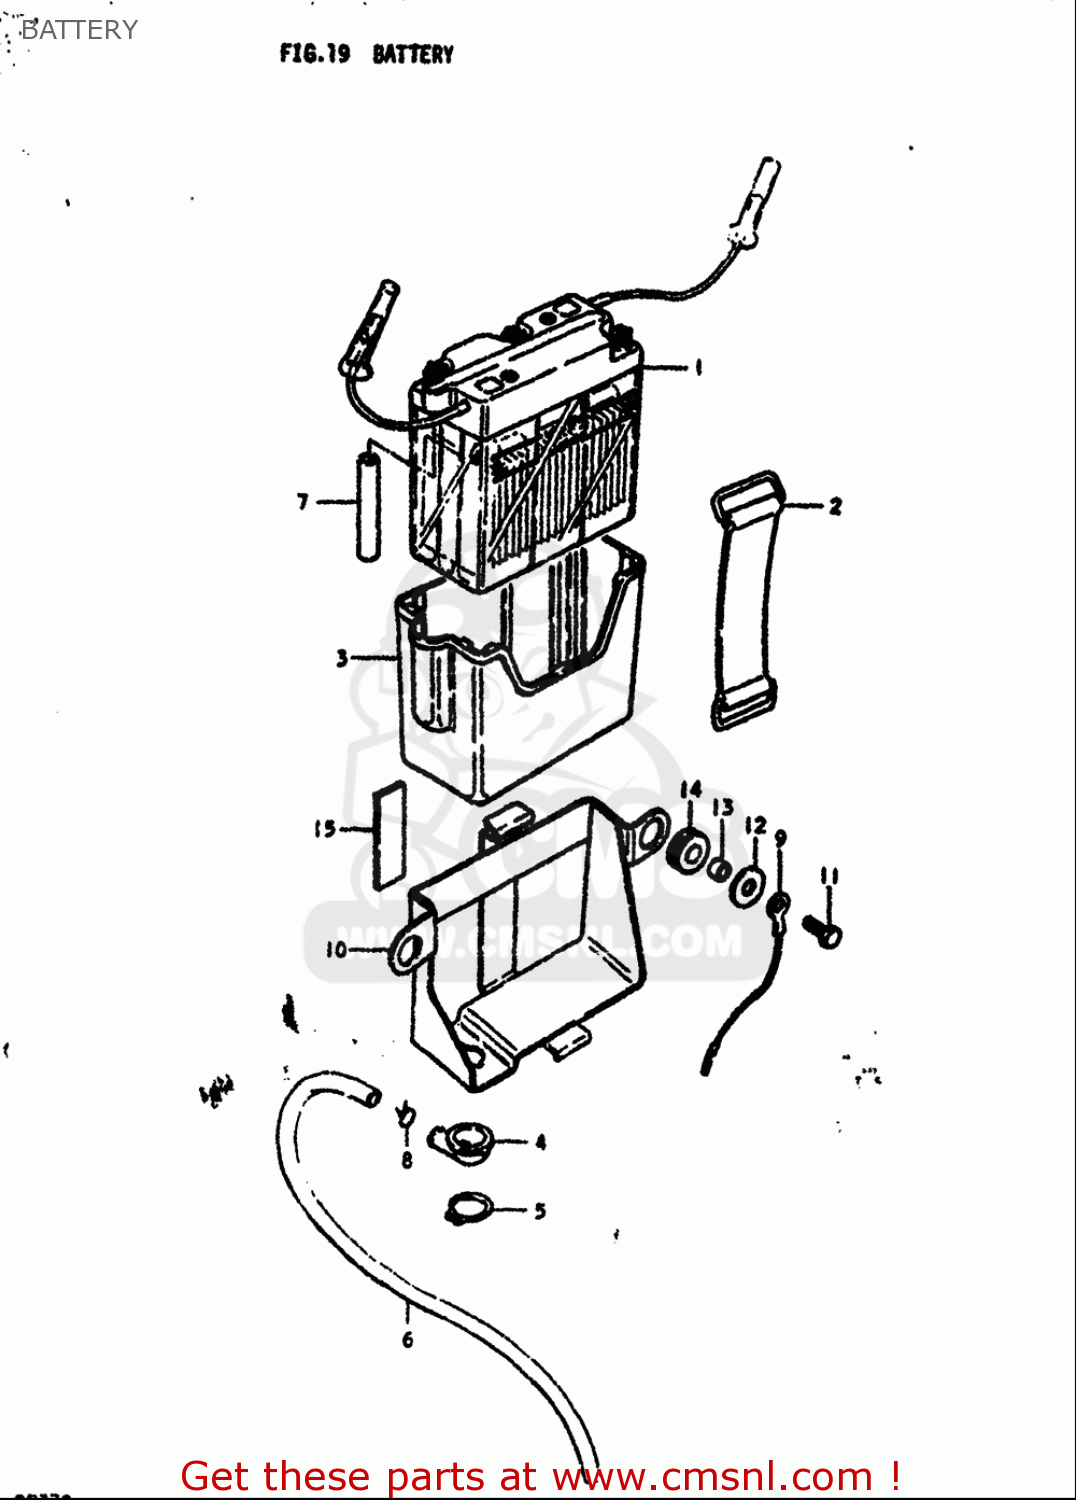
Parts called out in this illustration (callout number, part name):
1	BATTERY(6N4B-2A,6V4.2AH)
2	BAND
3	CASE,BATTERY
4	FUNNEL,BATTERY EXHAUST
5	CIRCLIP,17MM
6	HOSE,BATTERY EXHAUST(L:780)
7	HOSE,BATTERY EXHAUST(L:780)
8	CLIP
9	LEAD WIRE
11	BOLT
12	WASHER(6.5X20X1.2)
13	SPACER,6.5X9X7
14	CUSHION
15	PROTECTOR(170X95X3.0)
